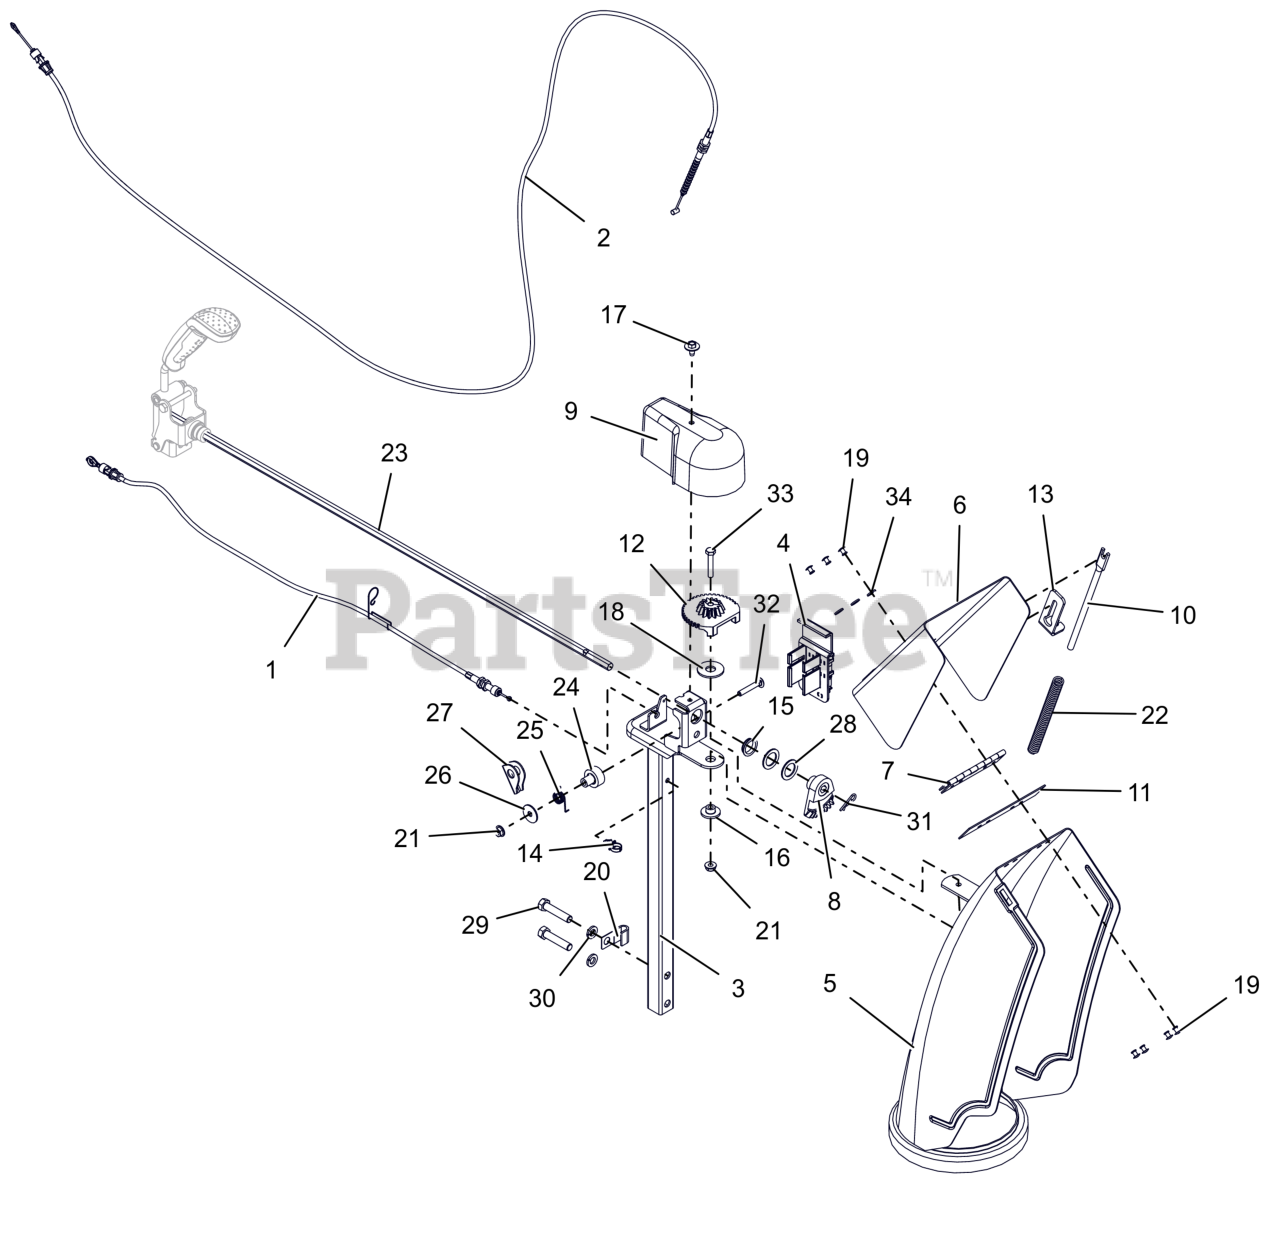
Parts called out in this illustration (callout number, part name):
1	CABLE, CHUTE LOCK, PRO
2	CABLE, DEFLECTOR - DELUXE
3	PEDESTAL, CHUTE - QUICK STICK
4	HOLDER W LARGE SHEAR BOLT /NUT
5	CHUTE,DISCHARGE,NOTCHED,QT
6	CAP, LARGE REMOTE W/DECAL
8	GEAR, CHUTE-ACTUATION
9	COVER, CHUTE GEAR
10	ROD, DEFLECTOR CAP
11	CAP SEAL 5.50
12	GEAR, CHUTE
13	BRACKET, ANCHOR-CHUTE CABLE
14	CLIP, CABLE GUIDE
15	BUSHING, POLYLINER-.75 SNAPIN
16	BSHG-FLG .265X.477X.375X1.00
17	SCR, TAP .25-20X.50 LG HWH ZCC
18	WSHR-FLT-NYL .515X1.375X.093
19	RVT, POP .1875 ZCC
20	J-CLAMP
21	NUT-LK-CTR-FLG .25-20 ZC120
22	SG-COMP .08X.40X6.50 14#/IN
23	ROD, HEX - CHUTE ROTATION
24	BUSHING, LOCK ARM
25	SG-TORS
26	WSHR,FLT .281X1.000X.063 ZCC
27	ARM, LOCKING
28	WSHR, FLT .754X1.125X.062 ZCC
29	BLT, HEX .38-16X1.75 G5 ZCC
30	WSHR,LK-REG .375X.094 ZCC
31	PIN, HAIR #213 .08X1.19 ZCC
32	BLT, RHSN .25-20X1.50 G5 ZCC
33	BLT, HEX .25-20X1.50 G5 ZCC
34	WSHR,FLT .196X.500X.066 ZCC
